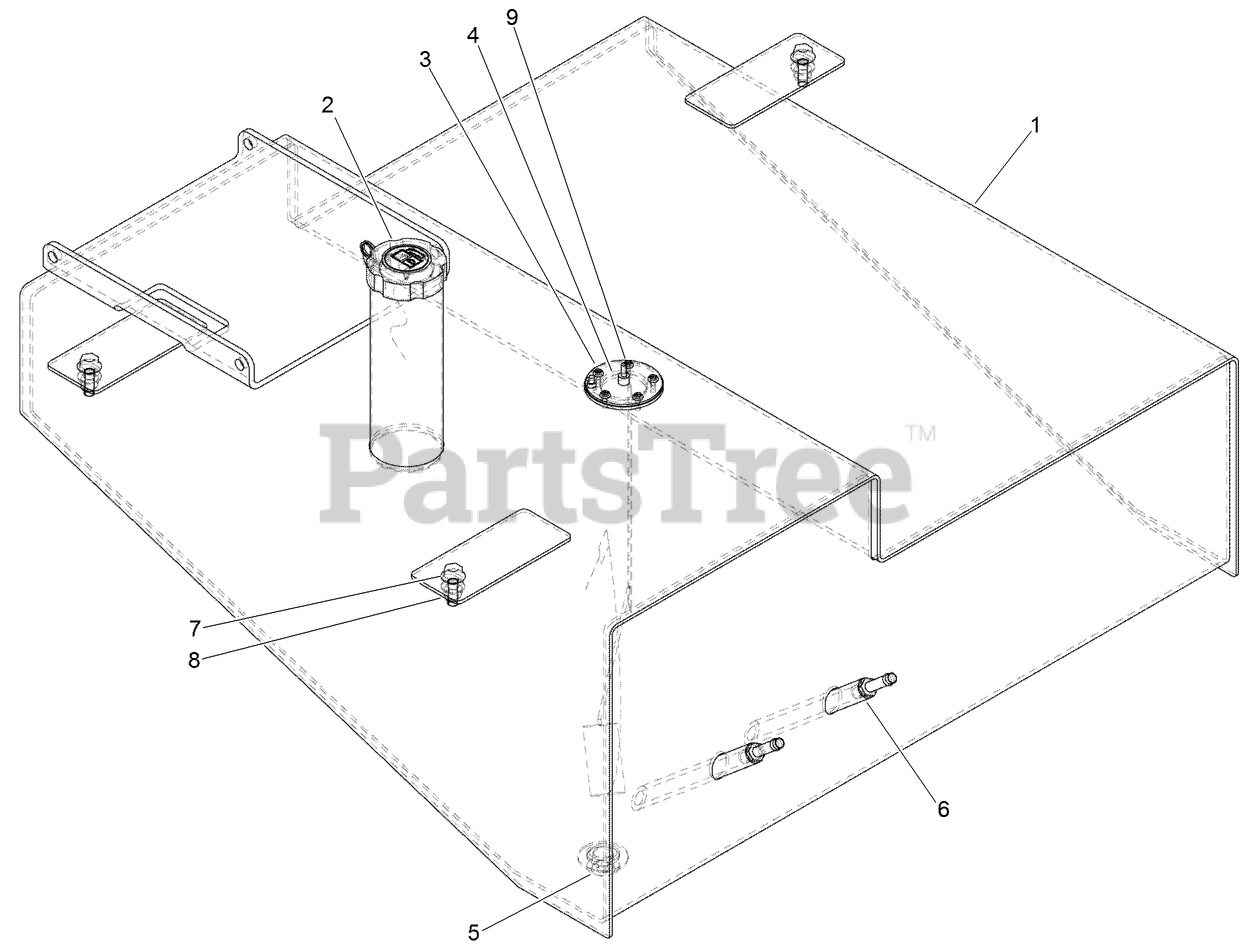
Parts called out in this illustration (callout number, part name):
1	TANK - Fuel
2	CAP-DIESEL FUEL W/ LOCK
3	GASKET-SENDING UNIT
4	SENDER-FUEL
5	PLUG-PIPE, HEX SOCKET
6	STEM-STRAIGHT, BEAD
7	SCREW-HH
8	NUT-FLANGE, NYLOCK
9	SCREW - Pan Hd Machine
